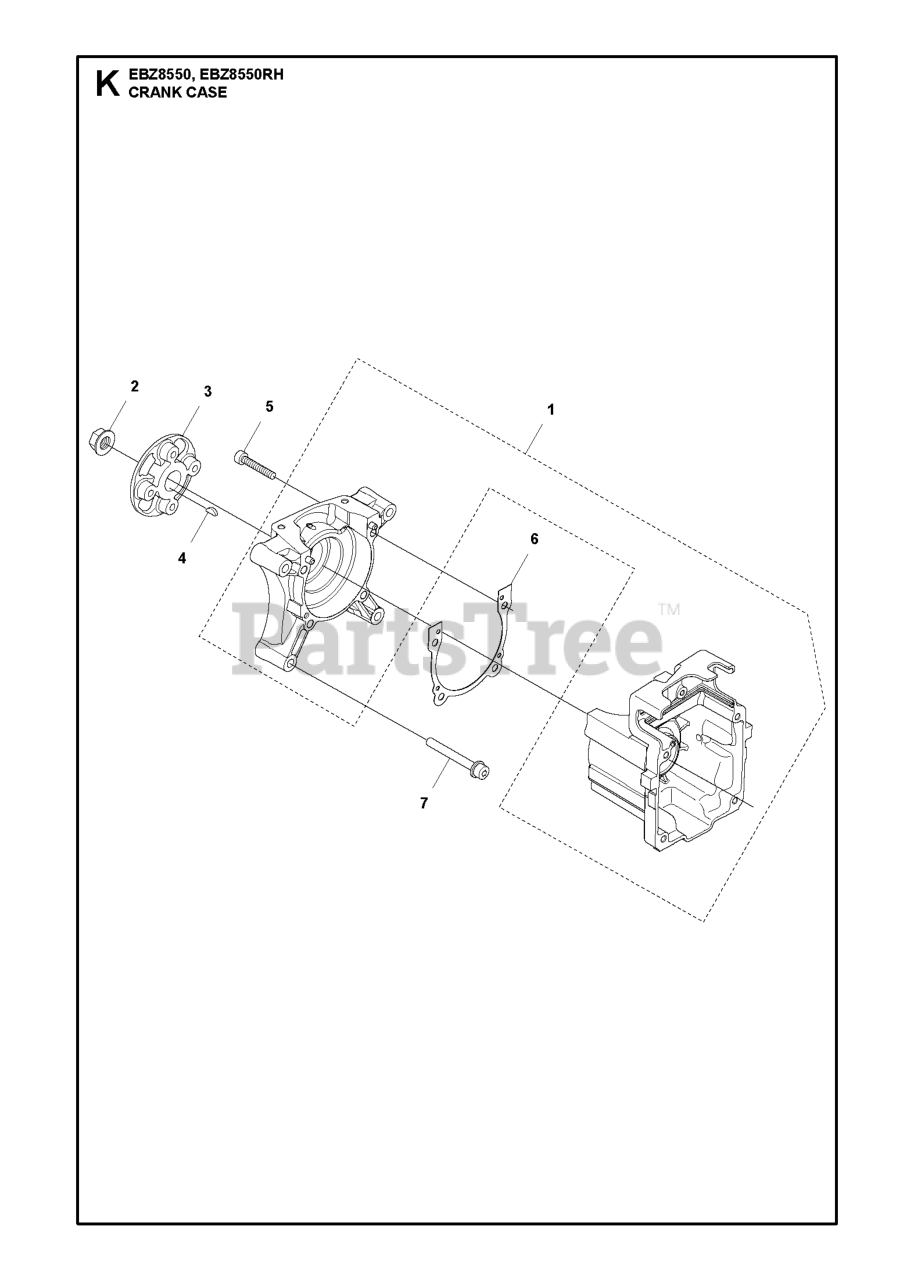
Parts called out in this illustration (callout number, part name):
1	CRANKCASE COMP
3	COUPLING
4	KEY
